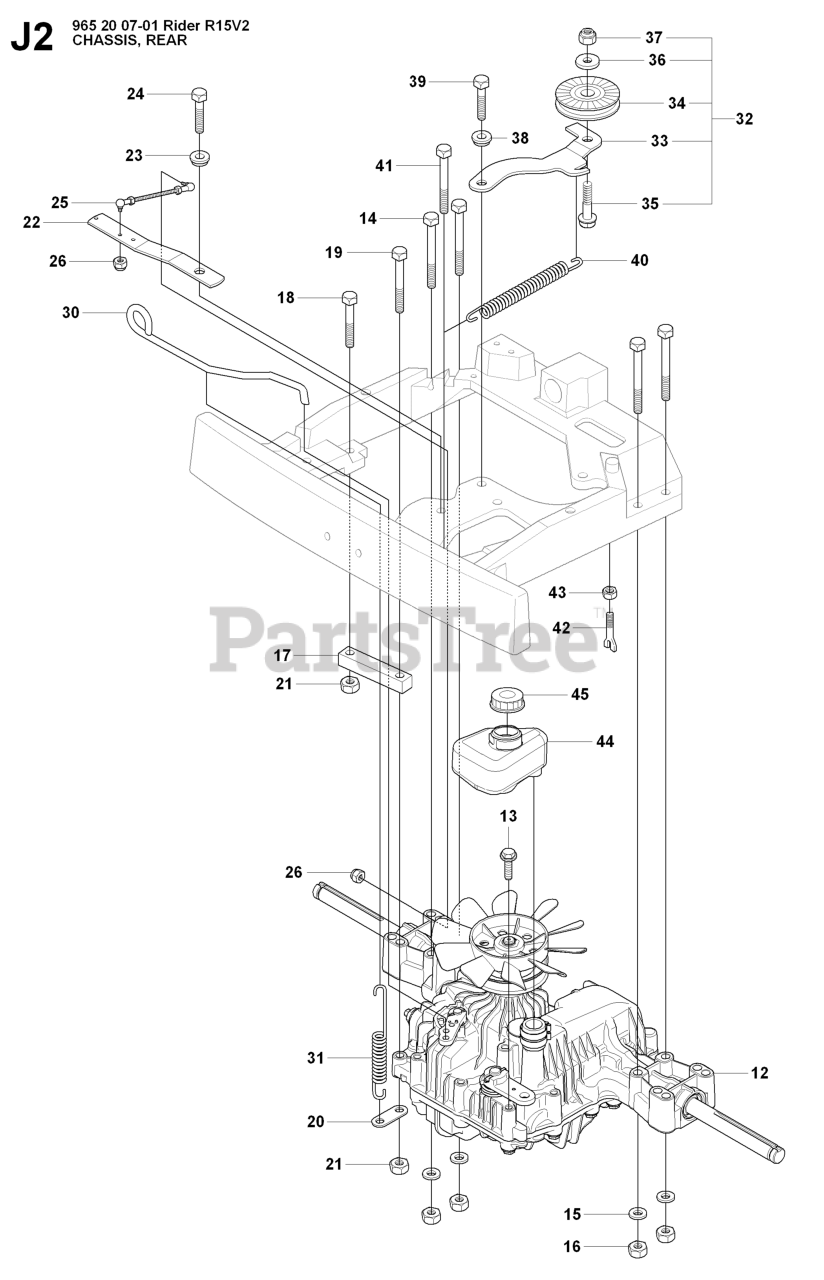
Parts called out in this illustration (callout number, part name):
12	HYDROSTAT 7A646024070
15	WASHER BRB 8.4X17
16	NUT
21	NUT
23	WASHER
24	SCREW 8X20
26	LOCKNUT M5
33	TENSIONER
35	SCREW
37	LOCKNUT M8
38	WASHER
39	SCREW 8X20
43	NUT
45	TANK CAP
